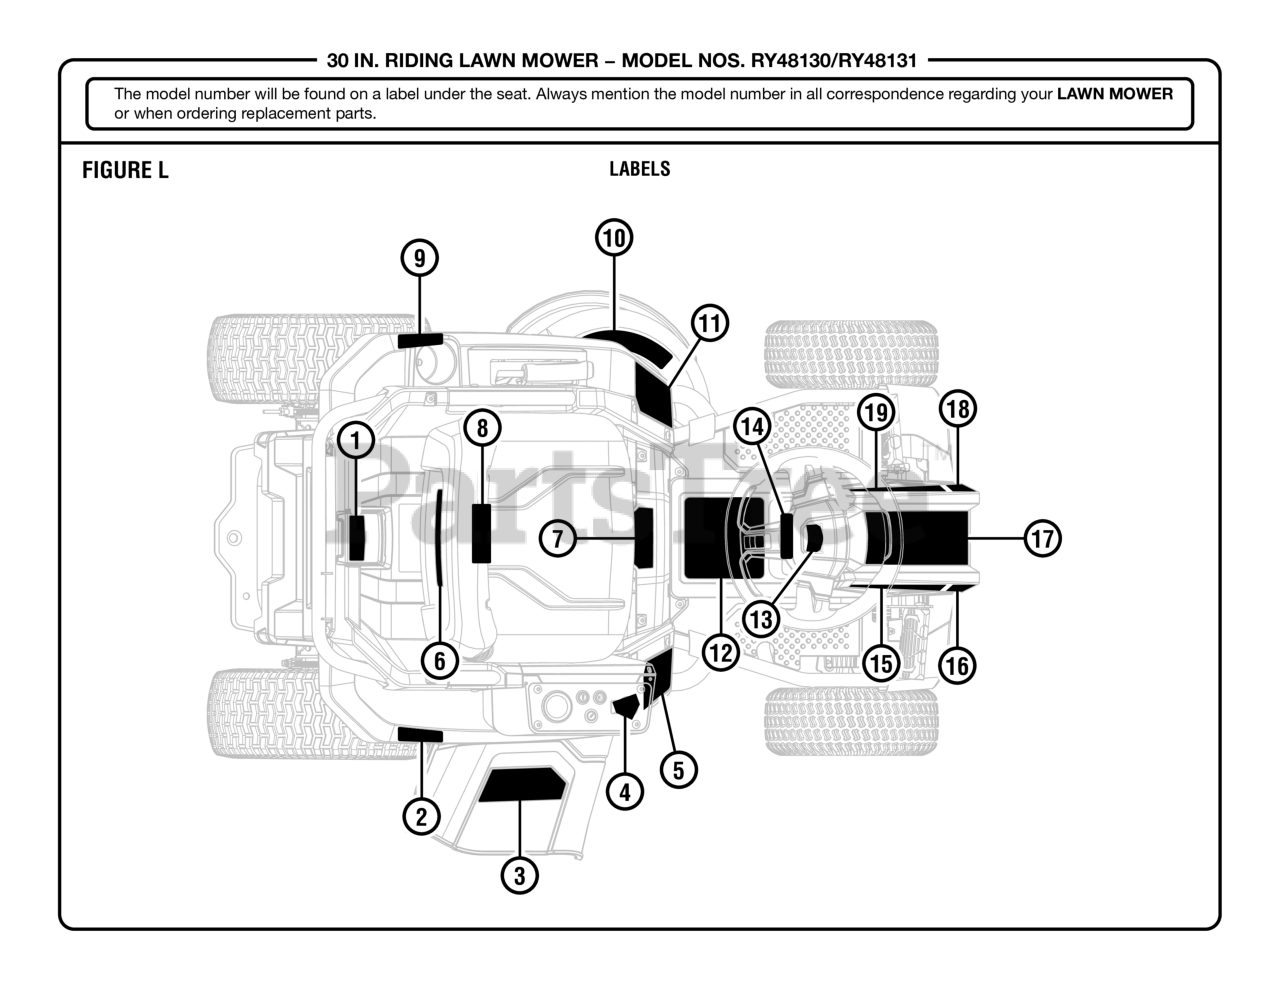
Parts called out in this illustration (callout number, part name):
1	Charging Port Label (Eng)
2	Logo Label (Right)
3	Discharge Chute Warnings Label (Eng)
4	No Hands CPSC Danger Label, English
5	Subbrand Logo Label (Right)
6	Logo Label (Rear Seat)
7	Blade Engagement Label (Eng)
9	Logo Label (Left)
10	Deck Warning Label (Eng)
11	Subbrand Logo Label
12	Warning Label (Eng)
13	Warning Instructions Label (Eng)
14	Parking Brake Pedal Label
15	Right Side Stripe (Upper)
16	Right Side Stripe (Lower)
17	Logo Label (Front)
18	Left Side Stripe (Lower)
19	Left Side Stripe (Upper)
